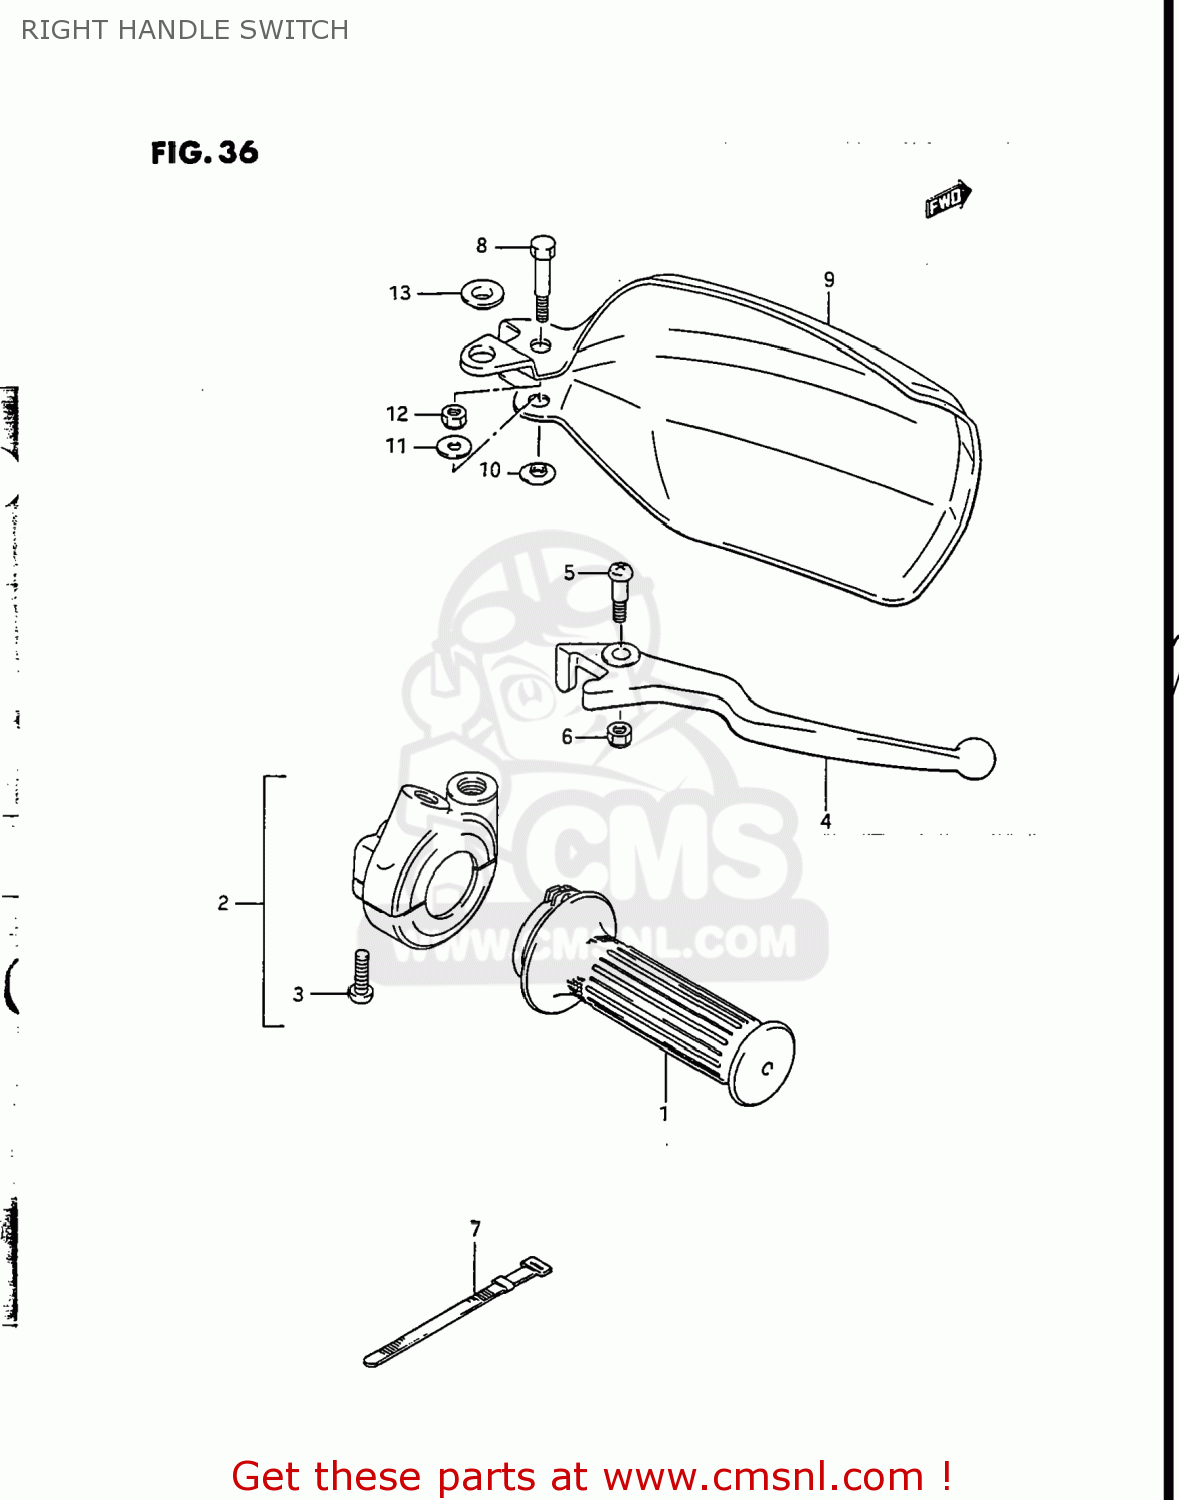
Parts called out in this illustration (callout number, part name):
1	GRIP,THROTTLE
2	CASE ASSY,THROTTLE
3	SCREW 5X20
4	LEVER,BRAKE
5	SCREW
6	NUT
7	CLAMP(L:120)
8	BOLT,LEVER PIVOT
9	COVER,KNUCKLE,RIGHT
10	WASHER
11	WASHER(6.5X16X1.2)
12	NUT 6MM
13	WASHER
